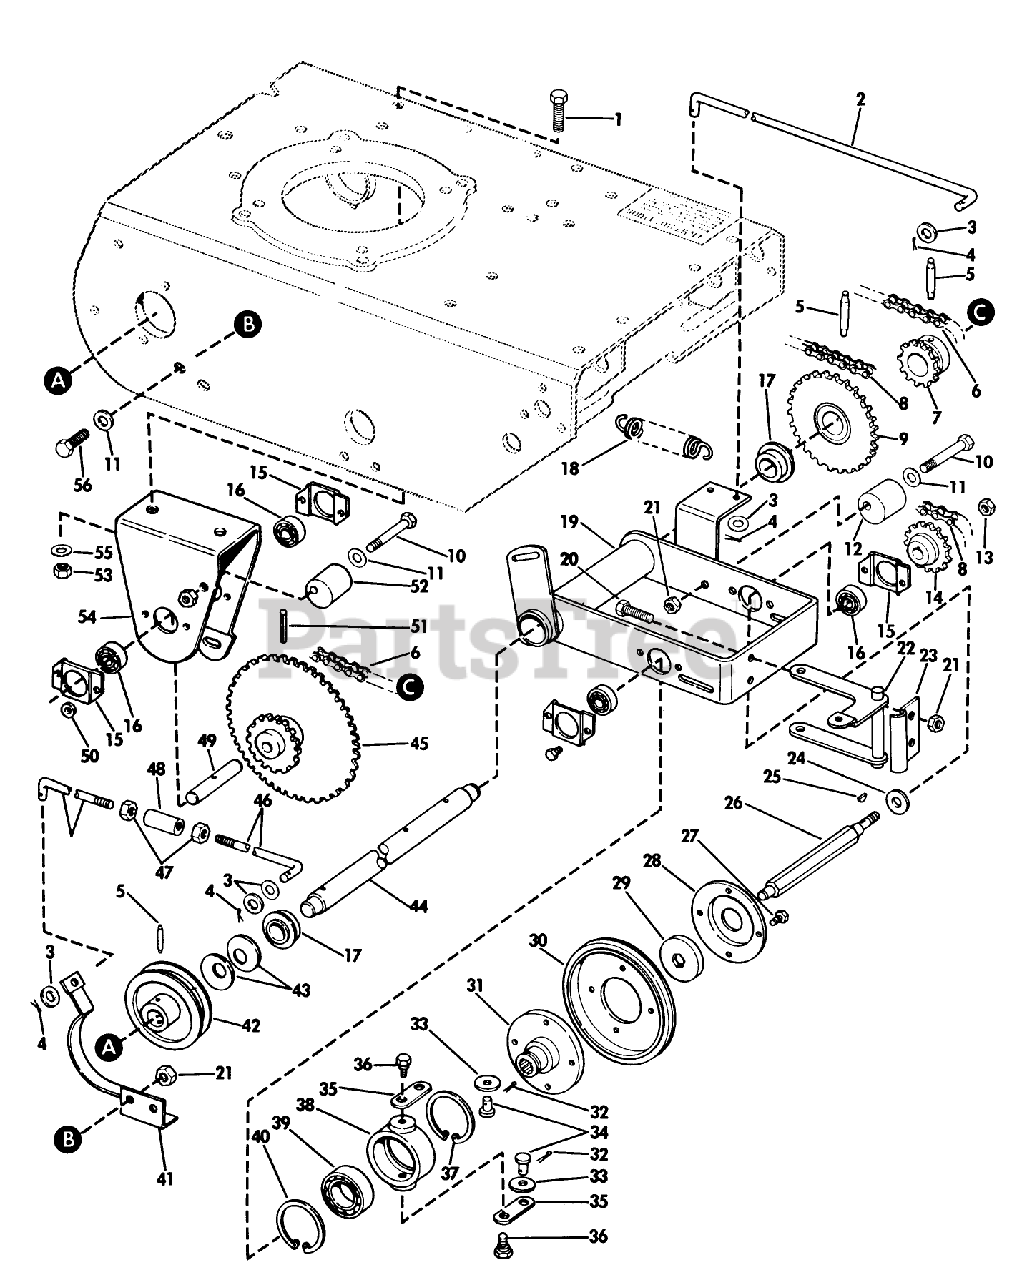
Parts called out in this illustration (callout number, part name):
13	LOCKNUT
30	DRIVE WHEEL
47	STOP NUT
53	LOCKNUT
